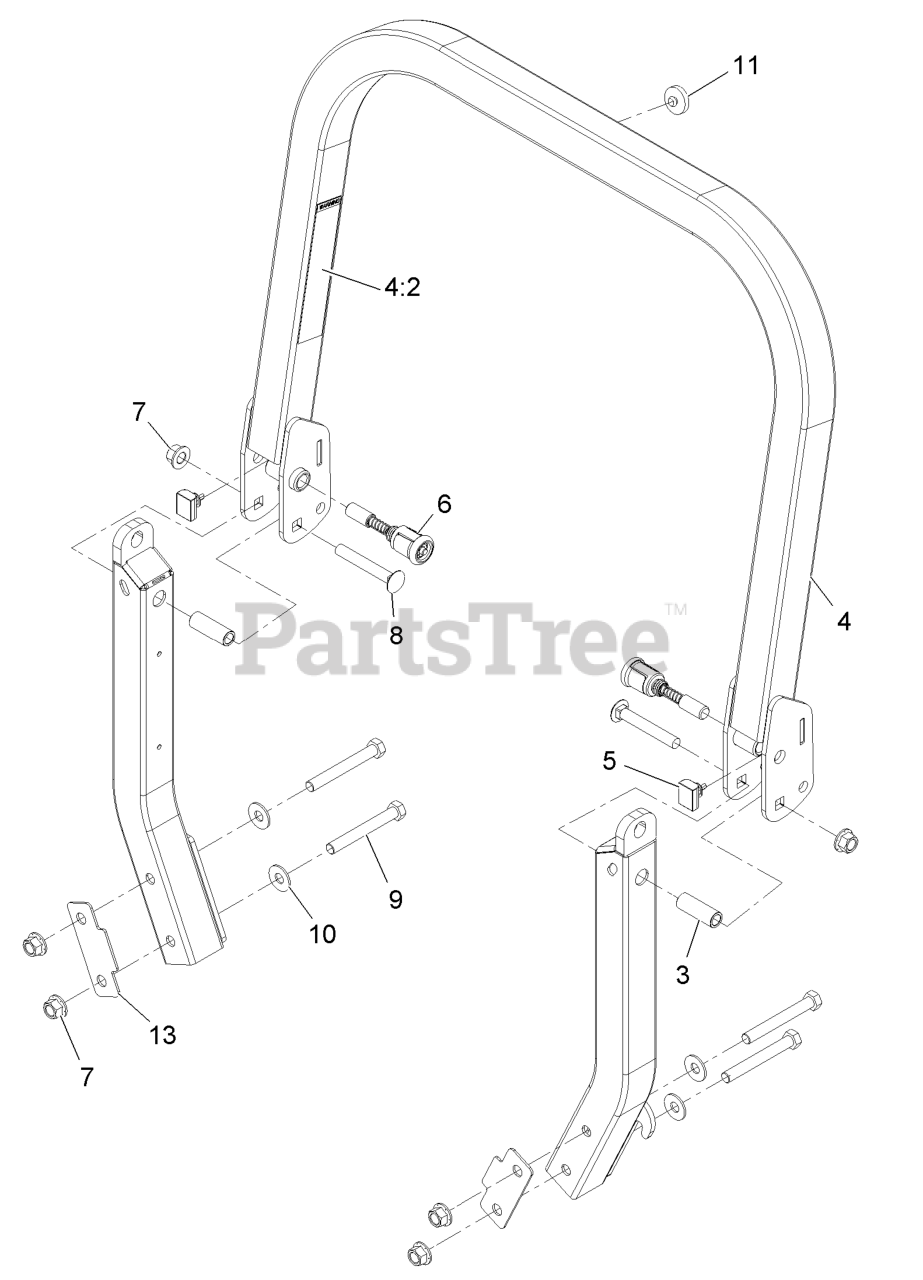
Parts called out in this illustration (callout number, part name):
4	UPPER ROPS ASM
4:2	DECAL-WARNING, FOLDING RO
5	BUMPER-ROPS
6	PIN-SPRING
7	Nut-Lock 1/2-13
8	SCREW-CARR
9	SCREW-HH
10	WASHER-SPRING
11	BUMPER-PUSH-IN, RUBBER
